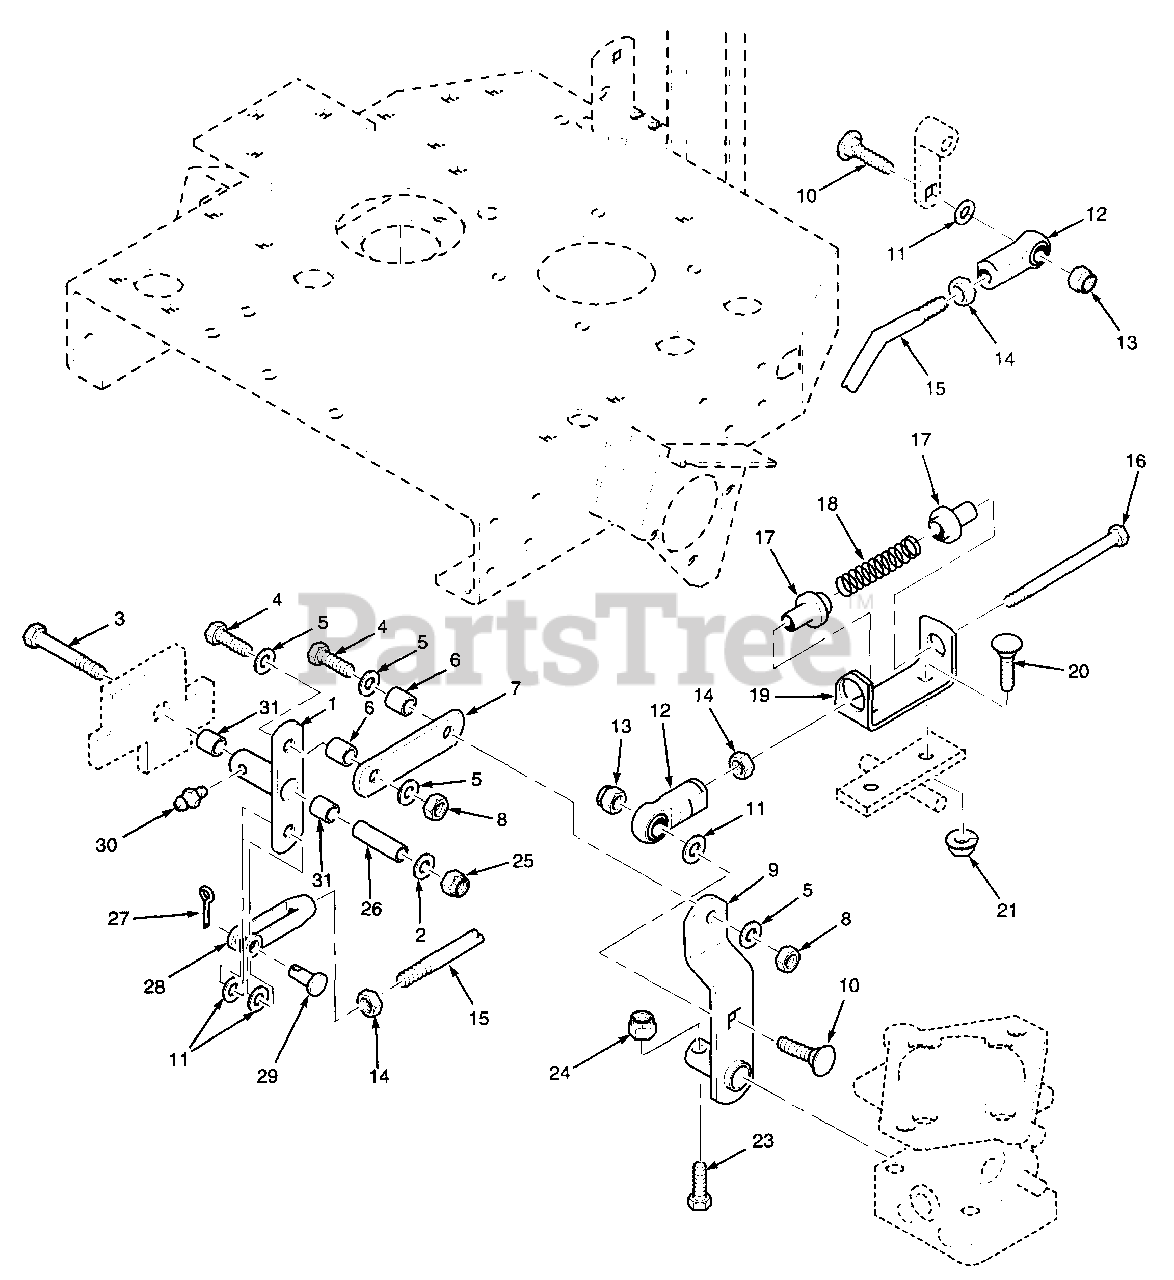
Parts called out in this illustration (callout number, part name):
1	Control Linkage, Bellcrank
2	Flatwasher, 5/16 (.375 x .875 x .083)
3	Bolt, Hex Head 5/16-18 x 2-3/4"
4	Bolt, Hex Head 3/8-16 x 1"
5	Flatwasher, 3/8 (.406 x .812 x .065)
6	Sleeve, Pump Control Link
7	Link, Speed Control
8	Hex Locknut, 3/8-16
9	Control Arm, Pump
10	Carriage Bolt, RH SH SQNK 3/8-16 x 1-1/2"
11	Flatwasher, 3/8 (.391 x .938 x .105)
12	Rod End, RH Female THD 3/8-24
13	Hex Locknut, Elastic Stop 3/8-16
14	Hex Nut, 3/8-24
15	Control Rod
16	Bolt Hex Head, 3/8-24 x 6-3/4"
17	Bushing, Spring Keeper
18	Spring, Neutral Return
19	Retainer, Neutral Spring
20	Carriage Bolt, 5/16-18 x 1"
21	Serr. Fl. Hex Nut 5/16-18
23	Bolt, Hex Head 1/4-20 x 1-1/4"
24	Hex Locknut, Elastic Stop 1/4-20
25	Hex Locknut, Elastic Stop 5/16-18
26	Sleeve, Control Arm
27	Cotter Pin, 3/32 x .75"
28	Clevis, Pump Control
29	Pin, Clevis 3/8"
30	Greese Fitting, 1/4-28 Self Tap
31	Bushing, Bronze
